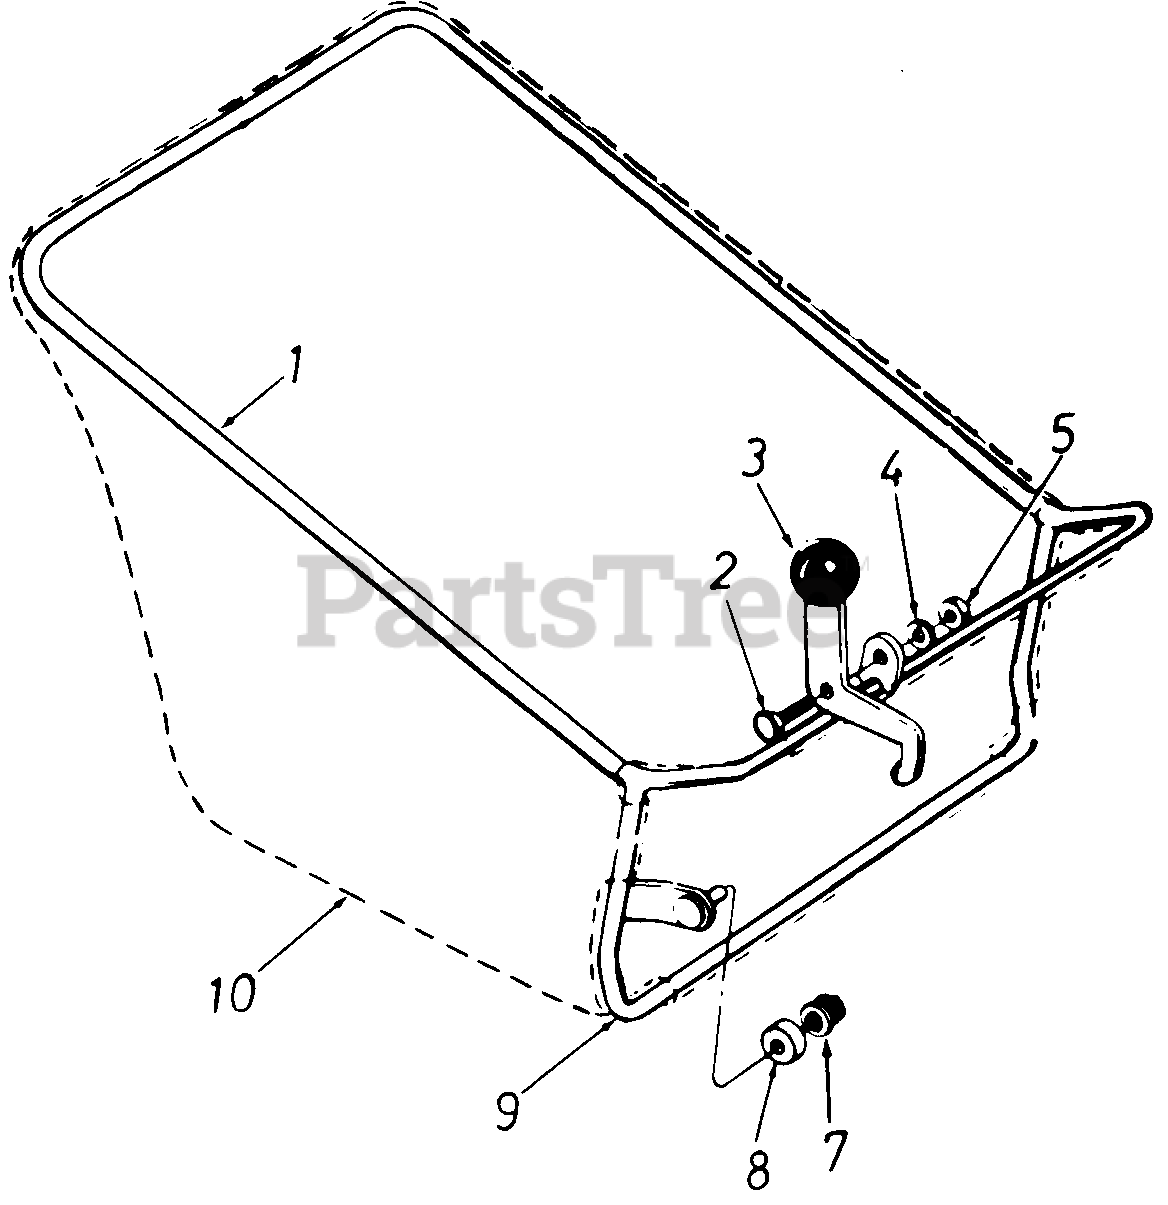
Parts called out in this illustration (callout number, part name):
1	Upper Frame
2	Shld. Scr. .437 Dia. x .180
3	Cam Lever Grip Ass'y.
4	L-Wash. 5/16" Scr.*
5	Hex Nut 5/16-18 Thd.*
7	Push Cap
8	Plastic Roller
9	Lower Frame Ass'y.
10	Grass Bag
